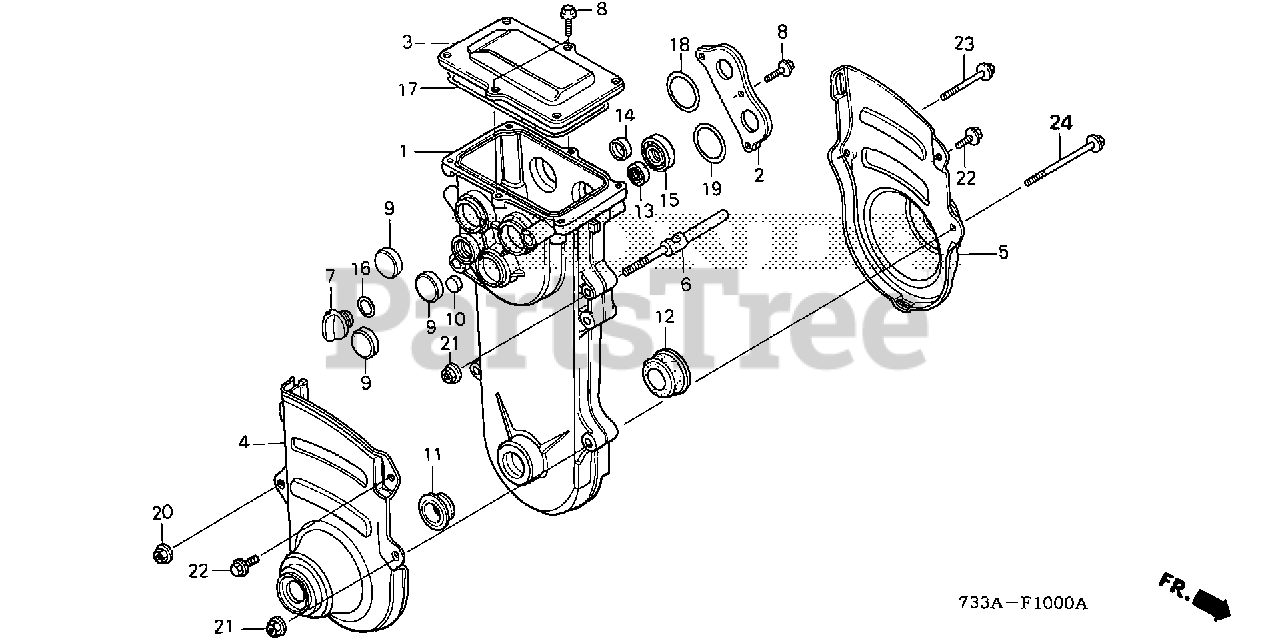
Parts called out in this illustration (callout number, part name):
1	CASE, TRANSMISSION
2	PLATE, BEARING HOLDER
3	COVER, TRANSMISSION CASE TOP
4	PROTECTOR, R. TRANSMISSION CASE
5	PROTECTOR, L. TRANSMISSION CASE (NA USE ALT:21921-733-305)
5	PROTECTOR, L. TRANSMISSION CASE
5	PROTECTOR, L. TRANSMISSION CASE (NOT AVAILABLE)
6	SHAFT, TENSIONER ARM
8	BOLT, FLANGE (6X12) (CT200)
9	PLUG, SEALING (28) (ARAI)
10	PLUG, SEALING (16) (ARAI)
11	SEAL, WATER (32X52X11) (ARAI)
11	SEAL, WATER (32X52X11) (NOK)
11	SEAL, WATER (32X52X10.5) (NOK)
12	SEAL, WATER (32X58X11) (ARAI)
12	SEAL, WATER (32X58X11) (NOK)
12	SEAL, WATER (32X58X10.5) (NOK)
14	PLUG, SEAL
15	OIL SEAL (15X35X7) (ARAI)
16	O-RING (16MM)
17	O-RING A, TRANSMISSION CASE
18	O-RING (40.5X2.5) (ARAI)
19	O-RING (45.5X2.5) (ARAI)
20	NUT, FLANGE (6MM)
21	NUT, FLANGE (8MM)
22	BOLT, FLANGE (6X10)
23	BOLT, FLANGE (6X32)
23	BOLT, FLANGE (6X40)
24	BOLT, FLANGE (8X55)
